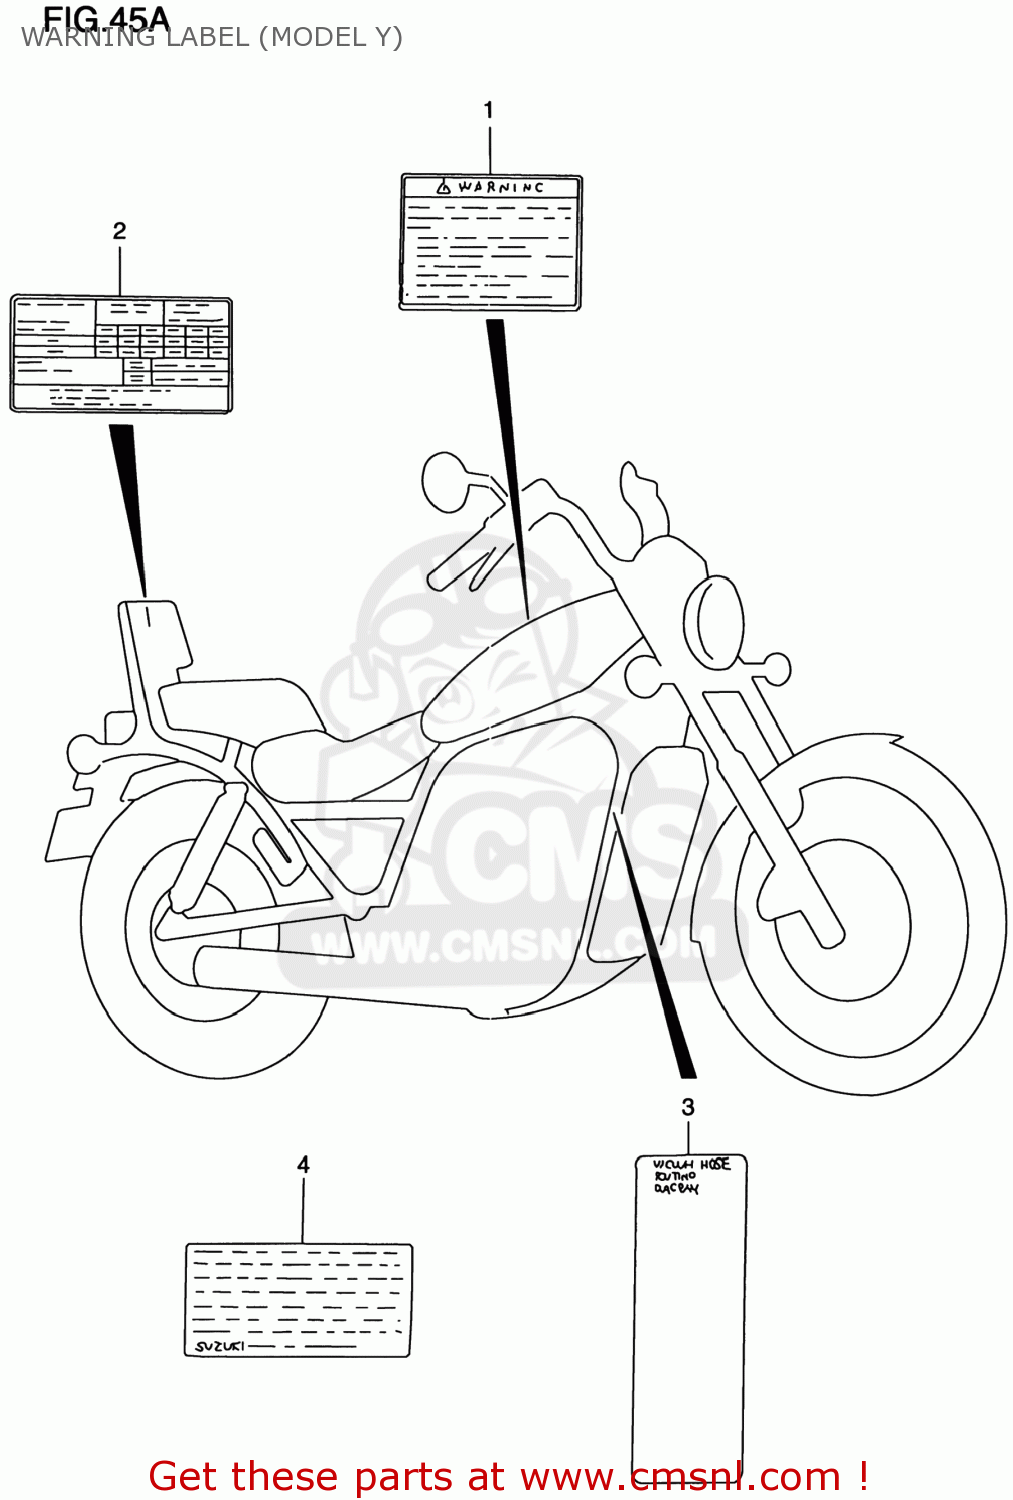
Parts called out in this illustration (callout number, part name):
1	LABEL,GENERAL WARNING
2	LABEL,TIRE INFORMATION
3	LABEL,VACUUM HOSE ROUTING
4	LABEL (MANUAL NOTICE)
